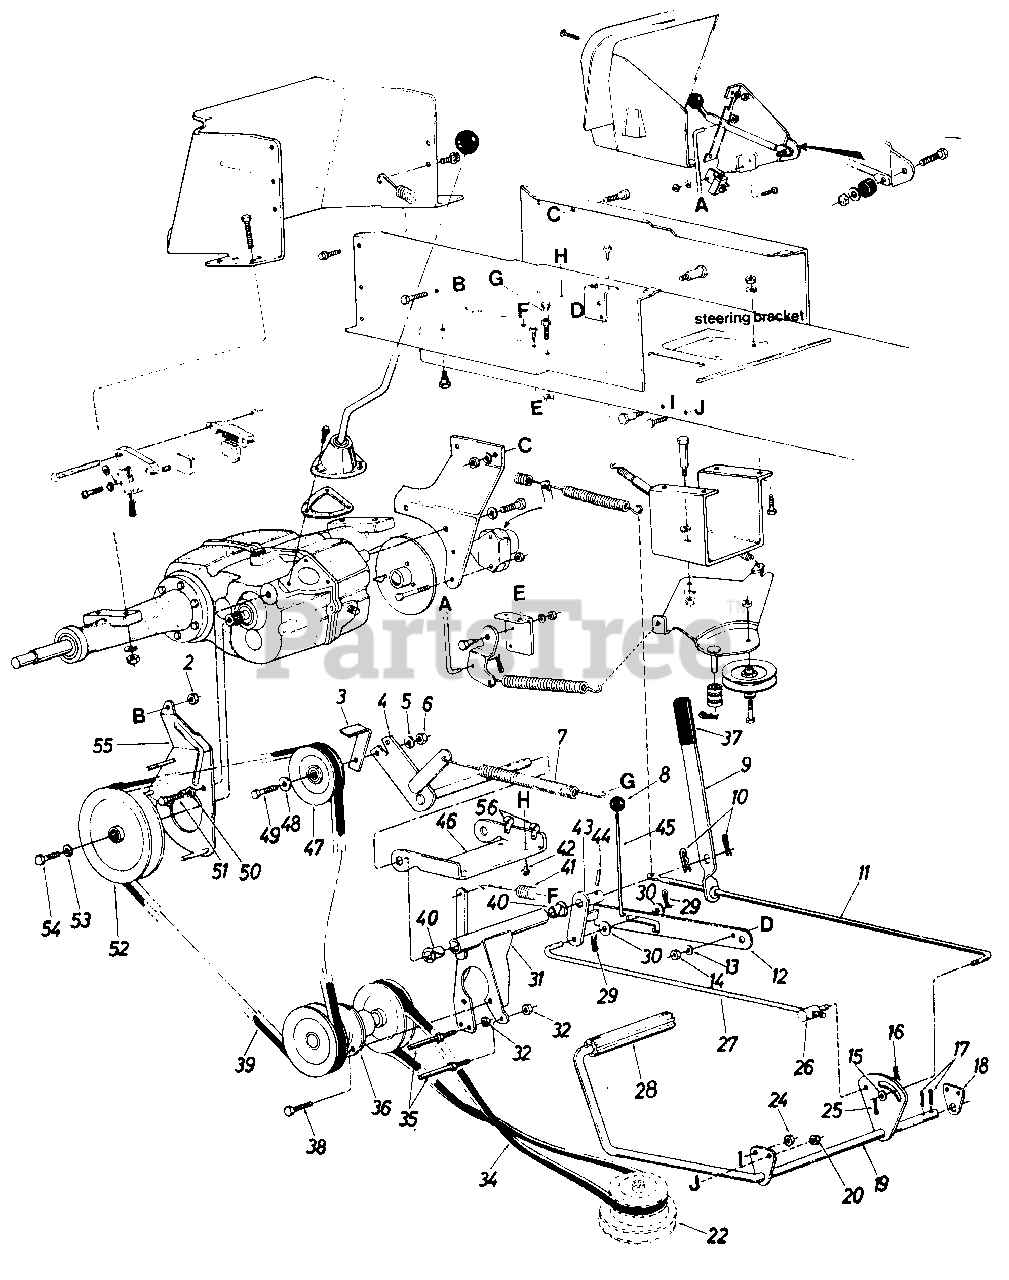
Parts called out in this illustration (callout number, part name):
2	Hex L Nut 3/8-16 Thd.
5	L-Wash. 3/8" Scr.
6	Hex Nut 3/8-16 Thd.
7	Ext. Spring
8	Knob
9	Hand Brake Lever
10	Hairpin Cotter 5/8" Dia.
11	Brake Rod
12	Parking Brake Cam
13	Fl-Wash. 5/16" Scr.
14	Hex Nut 5/16-18 Thd.
15	Fl-Wash. 5/16" Scr.
16	Hairpin Cotter 3/8" Rod
17	Cotter Pin 1/8" Dia. x 1.00" Lg. *
18	Clutch Rod Brg. Brkt.
19	Clutch-Brake Pedal Ass'y.
20	Hex Cent. L-Nut 3/8-16 Thd.
22	Engine Pulley 4.75 & 5.56
24	Hex Cent. L-Nut 3/8-16 Thd.
25	Cotter Pin 3/32" Dia. x .75" Lg. *
26	Pivot Bushing
27	Brake Cam Rod
28	Foot Pad
29	Hairpin Cotter 3/8" Rod
30	Fl-Wash. 818" I.D. x l.OO" O.D. x .030
31	Jack Shaft Mtg. Brkt. Ass'y.
32	Hex Top L-Nut 3/8-16 Thd.
34	"V"-Belt 1/2 x 59" Lg. (Polyester)
35	Stud 3/8-16 x 3.62" Lg. Special
36	Jack Shaft Ass'y.
37	Flat Grip
38	Hex Sem Scr. 5/16-18 x .75 Lg. *
39	"V"-Belt 1/2 x 40" Lg. (Kevlar)
40	Nyliner 5/8" I.D. x .88" Lg.
41	Ext. Spring
42	Hex Thd. Rolling Scr. 1/4-20 x .50" Lg.
43	Clutch-Idler Horn Ass'y.
44	Spring Pin Spiral 1/4" Dia. x 1.00" Lg
45	Parking Brake Link
46	Idler Mtg. Brkt.-Drive
47	4" "V"-Idler Pulley
48	Fl-Wash. 3/8" I.D.
49	Hex Scr. 3/8-16 x 1.75" Lg.
50	L-Wash. 3/8" Scr.*
51	Hex Scr. 3/8-16 x .75" Lg.
52	"V"-Pulley 7.0" O.D.
53	L-Wash. 3/8" Scr.
54	Hex Scr. 3/8-24 x .75" Lg.
55	Belt Guard Ass'y.
56	Plastic Hose Clamp
